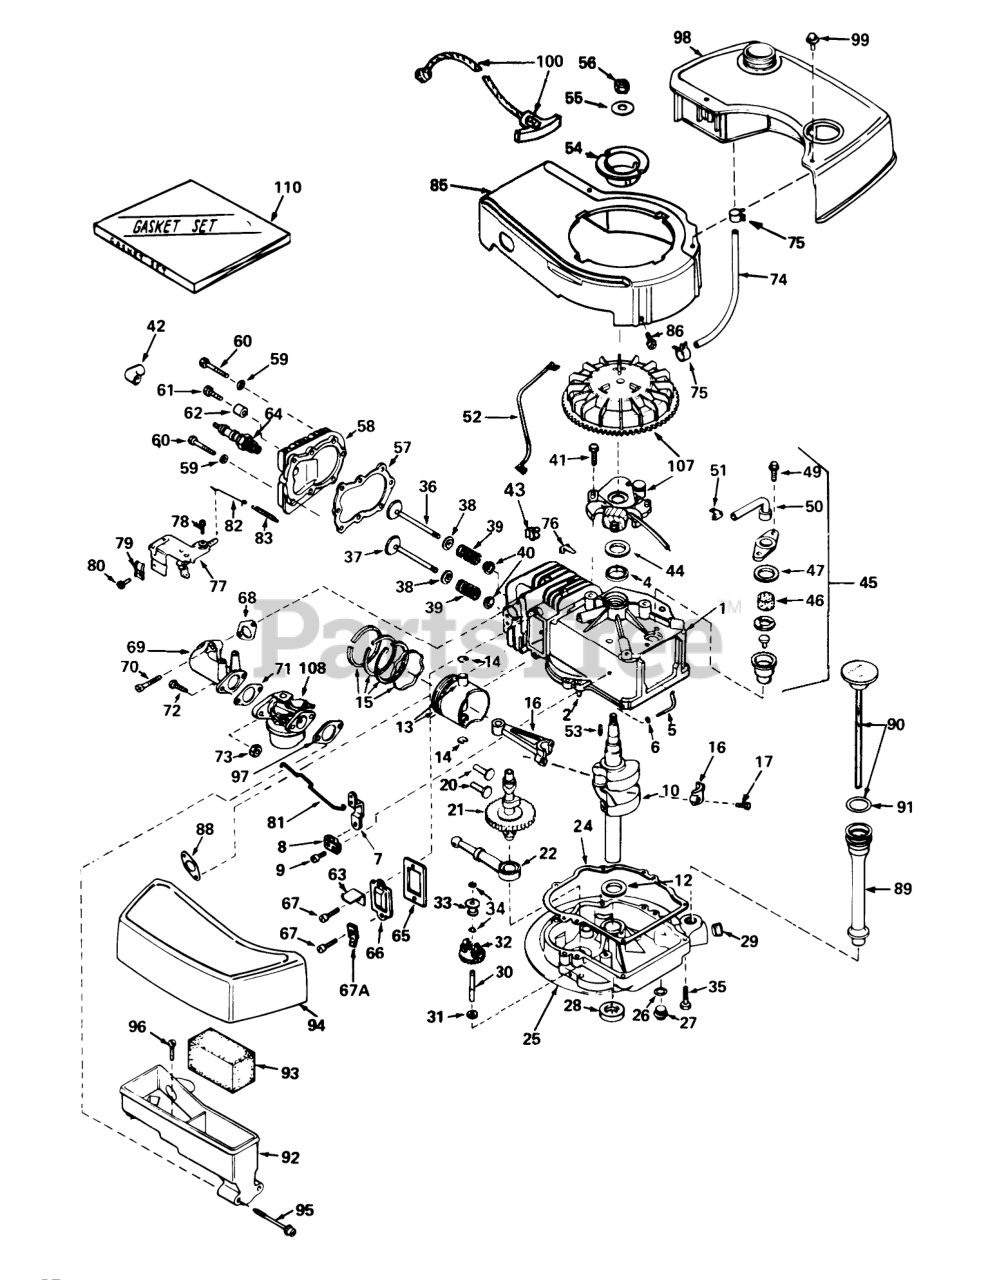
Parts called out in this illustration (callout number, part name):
1	Cylinder Assembly (Incl. Ref. #2, 4 & 87)
2	Pin-Dowel
4	Seal-Oil
5	Rod, Governor (Incl. Ref. #6)
6	Washer-Flat
7	Governor Lever
8	Clamp-Lever, Governor
9	Screw
10	Crankshaft
12	Washer-Thrust
13	Piston & Pin Assembly (Incl. 2 of No. 14)(Std.)
13	Piston & Pin Assembly (Incl. 2 of No. 14)(.010 Oversize)
13	Piston & Pin Assembly (Incl. 2 of No. 14)(.020 Oversize)
14	Ring-Retaining, Piston Pin
15	Ring Set-Piston Std.
15	Ring Set-Piston .010 oversize
15	Ring Set-Piston .020 oversize
16	Rod Assembly, Connecting (Incl. Ref. #17)
17	Bolt-Rod, Connecting
20	Lifter-Valve
21	Camshaft(Mech.Comp. Release)
22	Oil Pump ASM
24	Gasket, Mounting
25	Flange Assembly, Mounting (Incl. Ref. #27 thru 30)
26	Gasket-Oil Drain
27	Plug Oil Drain
28	Seal-Oil
29	Plug Oil Drain
30	Shaft-Governor
31	Washer-Flat
32	Gear Assembly, Governor (Incl. Ref. #31)
33	Spool-Governor
34	Ring-Retaining
35	Screw (1/4-20 x 1-1/4)
36	Valve, Intake (Incl. Ref. #38 thru 40)(Std.)
36	Valve, Intake (Incl. Ref. #38 thru 40)(1/32" Oversize)
37	Valve, Exhaust (Incl. Ref. #38 thru 40)(Std.)
37	Valve, Exhaust (Incl. Ref. #38 thru 40)(1/32" Oversize)
38	Cap-Upper Valve Spring
39	Spring-Valve
40	Cap-Valve, Spring
42	Cover-Spark Plug
43	Clip, Wire
44	Gasket Stator
45	Breather Assembly (Incl. Ref. #46, 47, 49 & 50)
46	Element-Breather
47	Gasket-Breather
49	Screw, Hex Hd. w/Conical
50	Tube, Breaker
51	Clip, Breather
52	Wire, Ground
53	Key, Flywheel
54	Pulley Starter
55	Washer-Spring
56	Hex Nut
57	Oil Fill Tube
58	Head Cylinder
60	Screw
61	Screw Hex Hd. Cap
63	Retainer Clip
64	Plug, Spark (Champion RCJ-8)
65	Gasket-Breather
66	Cover-Valve
67A	Terminal
68	Gasket, Intake
69	Pipe, Intake
70	Screw (1/4-20 x 1)
71	Gasket-Carburetor
72	Screw
73	Nut and Lock Washer (1/4-28)
74	Line-Fuel
75	Clamp-Line, Fuel
76	Clip-Wire
77	Control Assembly, Speed
78	Screw (10-24 x 3/4)
79	Conduit
80	Screw (10-32 x 3/8)
81	Link Governor
82	Link Governor Spring
83	Spring Governor
85	53024/VAR.GT O/P W/
86	Screw
88	Gasket Exhaust
89	Tube Fill
90	Dipstick, Oil (Incl. Ref. #91)
92	Body Air Cleaner
93	Filer, Air
94	Cove, Air Cleaner
95	Screw Fil Hd.
96	Screw, Hex Hd.
97	Gasket-Air Cleaner
98	Tank Fuel
99	Screw (10-32 x 35/64)
100	Rope Assy., Starter
107	Magneto
108	Carburetor (Incl. Ref. #71)
110	53024/VAR.16HP O/P
